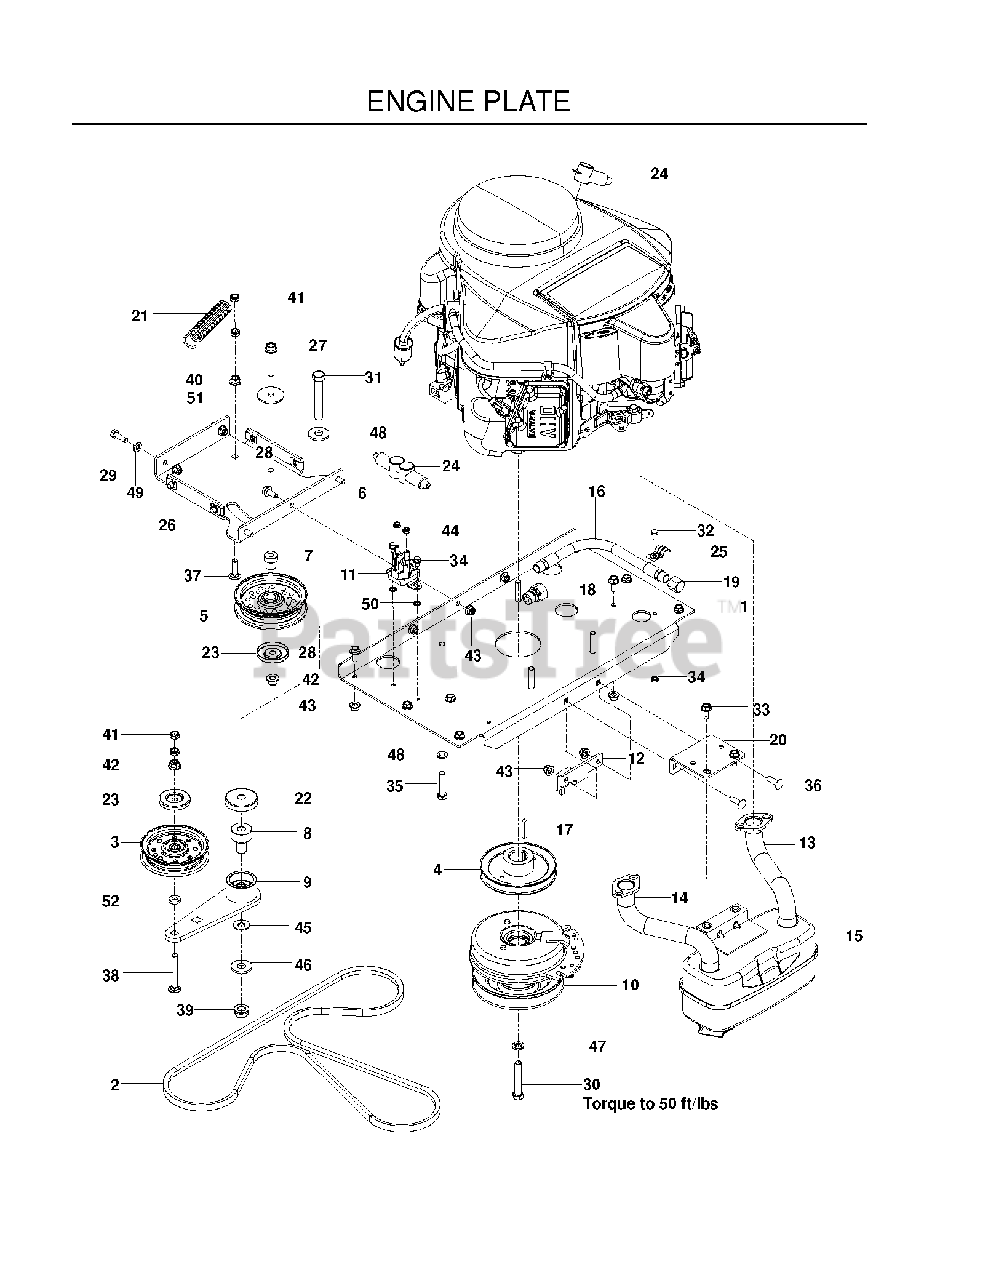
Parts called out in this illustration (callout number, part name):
1	PLATE, ENGINE W/DECALS
2	BELT, HYDRO, 3400
3	FLAT IDLER PULLEY
4	PULLEY, V, 1.125 BORE
5	IDLER PULLEY
6	PLATE, IDLER, BLK
7	PIVOT, IDLER
8	PIVOT, BEARING
9	ARM, IDLER, STEEL, W/BGS
10	CLUTCH 200 FT LB
12	STOP, CLUTCH, BLACK
13	TUBE.EXHAUST.LH.FR961/FR730
14	TUBE.EXHAUST.RH.FR961/FR730
15	MUFFLER ASM TWIN
16	OIL DRAIN HOSE
17	KEY, 1/4 SQ X 1 1/4
18	ADAPTER, OIL DRAIN
20	BRKT, MUFFLER, BLK
21	SPRING, PUMP
22	SHIELD, DUST
23	DUST SHIELD
26	U-CLIP 5/16-18 NUT RETAINER
27	HHFS 3/8-16 X 2.0 GD 5
28	HHFS 5/16-18 X 3/4
29	HCS 5/16C X 1
30	BOLT 7/16F X 2 1/2
31	HCS 1/2C X 3 1/4
32	HCS 1/4-20.
33	BOLT 5/16-18 X 3/4
34	HWST 1/4C X 3/8
35	BOLT, HCS 3/8-16X1-3/4
36	RHSSNB 5/16C X 1.0
37	RHSNB 3/8-16 X 1-1/4
38	RHSNB 3/8-16 X 2.75
39	NUT, 1/2-13 HEX FLG NYLOC ZD
40	NUT 3/8C WHIZ
41	NUT HEX 3/8-16 NYLON, THIN
42	NUT 3/8-16 HEX FLG NYLOC ZD
43	5/16-18 NYLOC FLANGE NUT
44	JAM NUT 1/4C (2 2 PW01)
45	CONTACT BELLSPR 1/2
46	WASH USS FLAT 1/2
47	WASHER 7/16 LOCK
48	SLW 3/8 STD
49	FLAT WASHER 5/16 SAE
50	WASHER 1/4 INT TOOTH
51	WASHER, 3/8 SPEC
52	WASHER 3/8 X 3/4 X .187 TK
